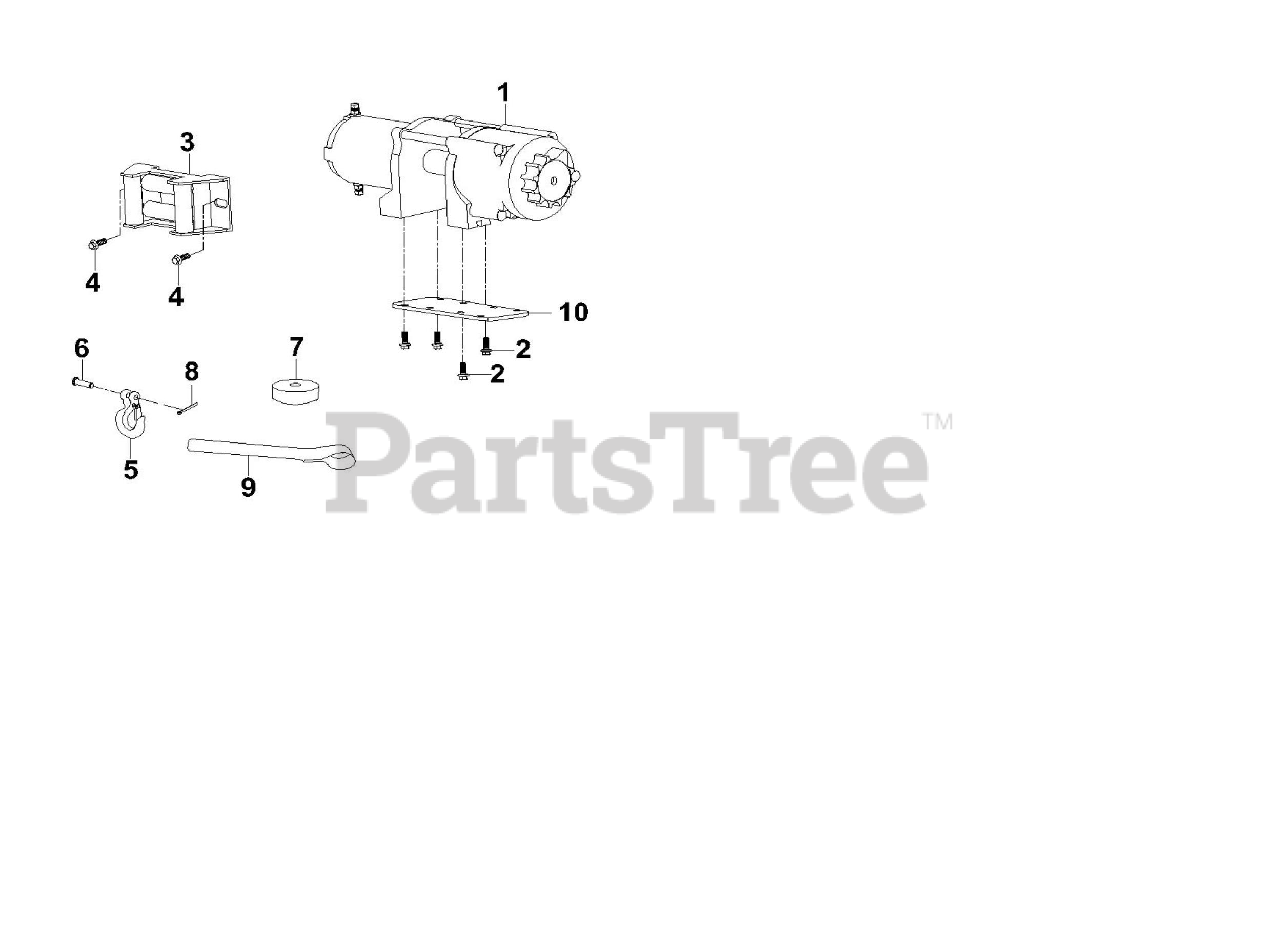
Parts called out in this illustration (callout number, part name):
1	Winch body
2	Hexagon Flange Bolt M8x20
3	Winch guide pulley
4	Hexagon Flange Bolt M8x20
5	Load hook
6	Pin 9.5x40
7	Plastic clasp
8	PIN - COTTER 2x30
10	WINCH BRACKET PLATED
